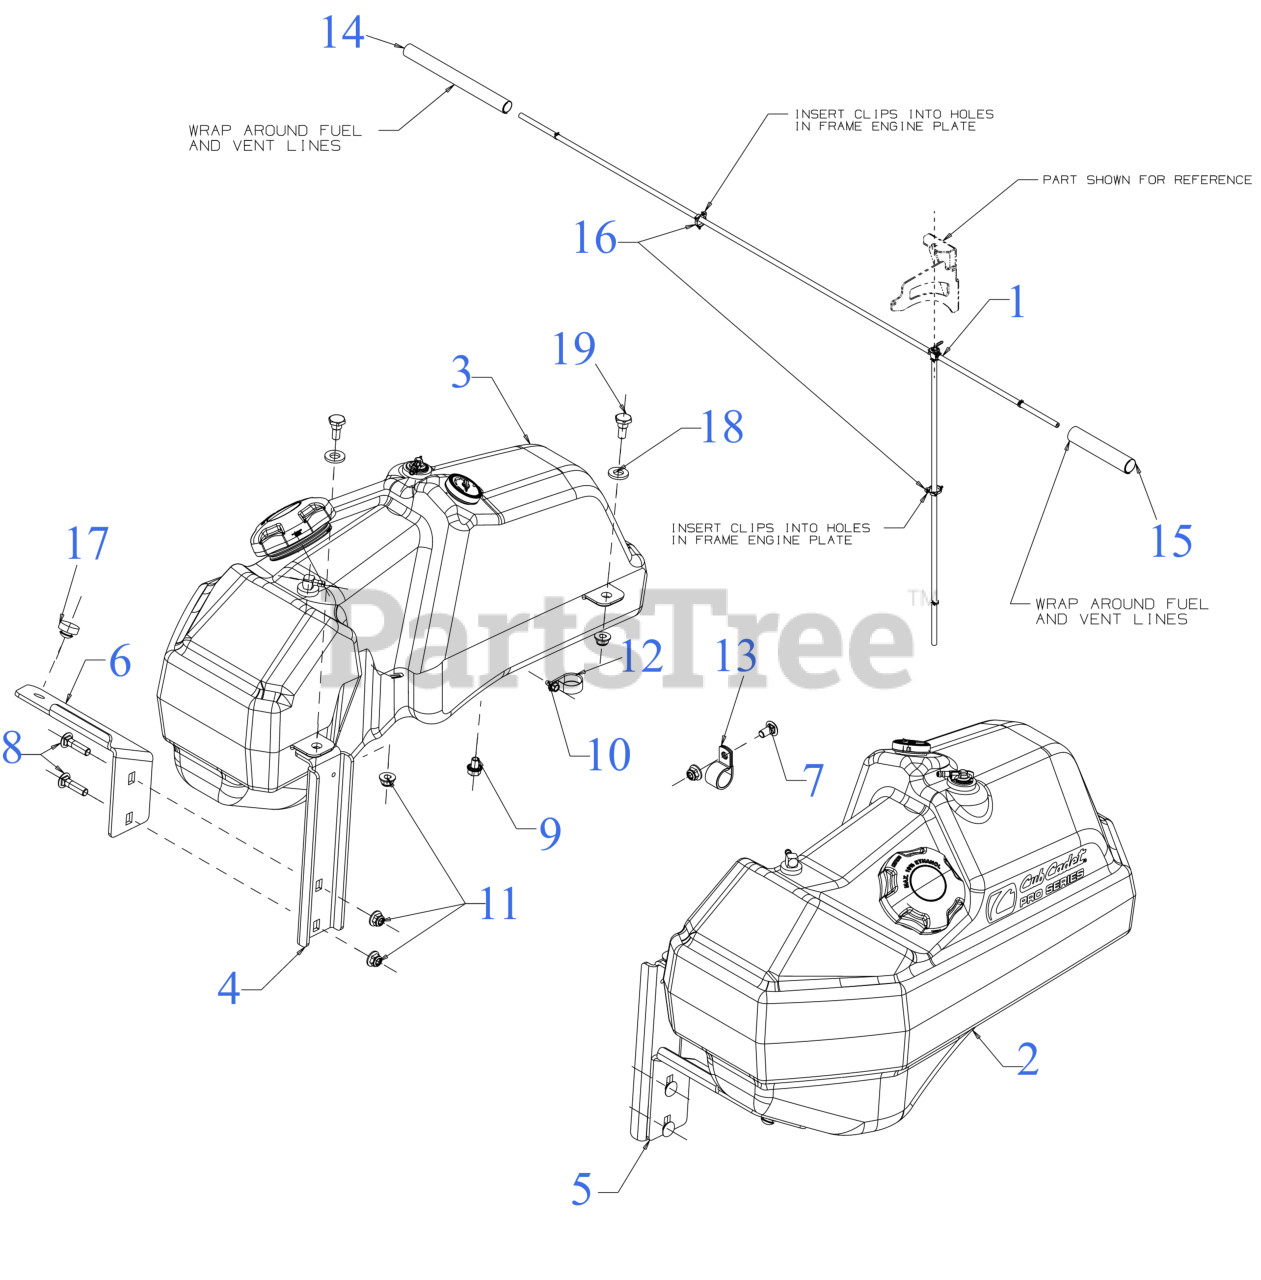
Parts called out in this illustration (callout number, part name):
1	FUEL HOSE W/VALVE
1	HOSE CLAMP 1/20
2	TANK ASM (RH) (7.25 GAL)
3	TANK ASM (LH) (7.25 GAL)
4	FUEL TANK MOUNTING BRACKET
7	CARRIAGE BOLT 3/8-16 x .750 GR5
8	CARRIAGE BOLT 3/8-16 x 1.50
9	SCREW 3/8-16 x .500 GR5
10	SCREW 1/4-20 X.500
12	DRAIN HOSE CLAMP
13	HOSE CLAMP 1.0"
14	WRAP AROUND SLEEVE 14"
15	WRAP AROUND SLEEVE 8"
17	RUBBER BUMPER 1.000 x .313
18	FLAT WASHER .510 x 1.000 x .125
19	SHOULDER SCREW .498 DIA x .340
